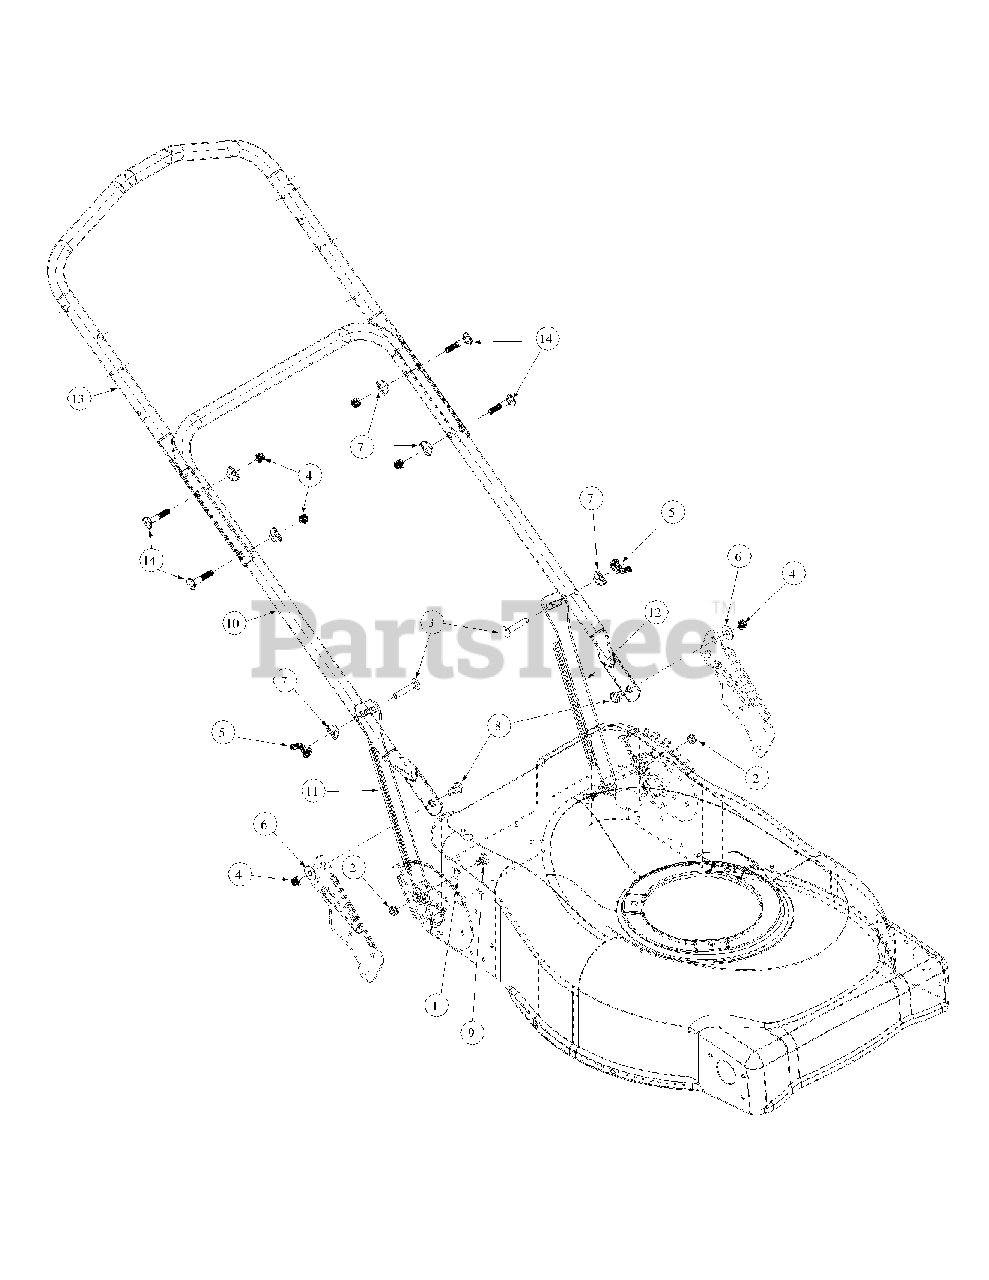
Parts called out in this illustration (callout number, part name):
1	Thrust Washer
2	Nut, Lock, 5/16-18,
3	Bolt Carriage, 5/16-18, 1.75
4	Hex Nut, 5/16-18
5	Wing Nut, 5/16-18
6	Belle Washer, .325 x .930 x .045
7	Shoulder Washer, .320 ID x .93 OD
8	Shoulder Screw, .435 x .350, 5/16-18
9	Shoulder Screw, .437 x 1.62 LG
10	Handle, Lower, 1.0"
11	Strut, 3 Position Handle, Right hand
12	Strut, 3 Position Handle, Left hand
13	Upper Handle, 1.0", Self Propelled
14	Carrige Bolt, 5/16-18 x 2.0 CRVD
